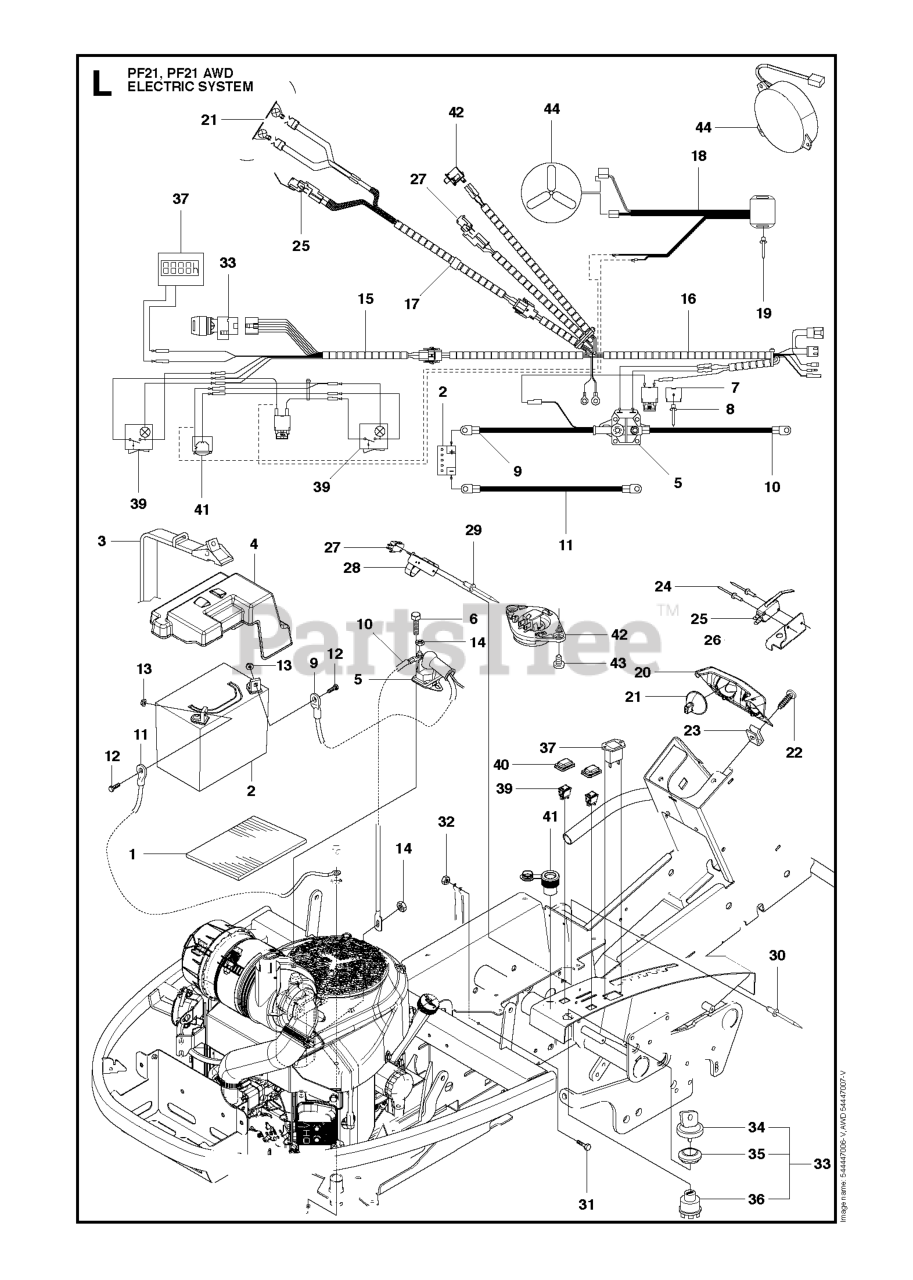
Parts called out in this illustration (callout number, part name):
9	CABLE
12	SCREW EHHM
19	RIVET
25	MICRO SWITCH
42	ANTI-START SWITCH CPL
43	SCREW
